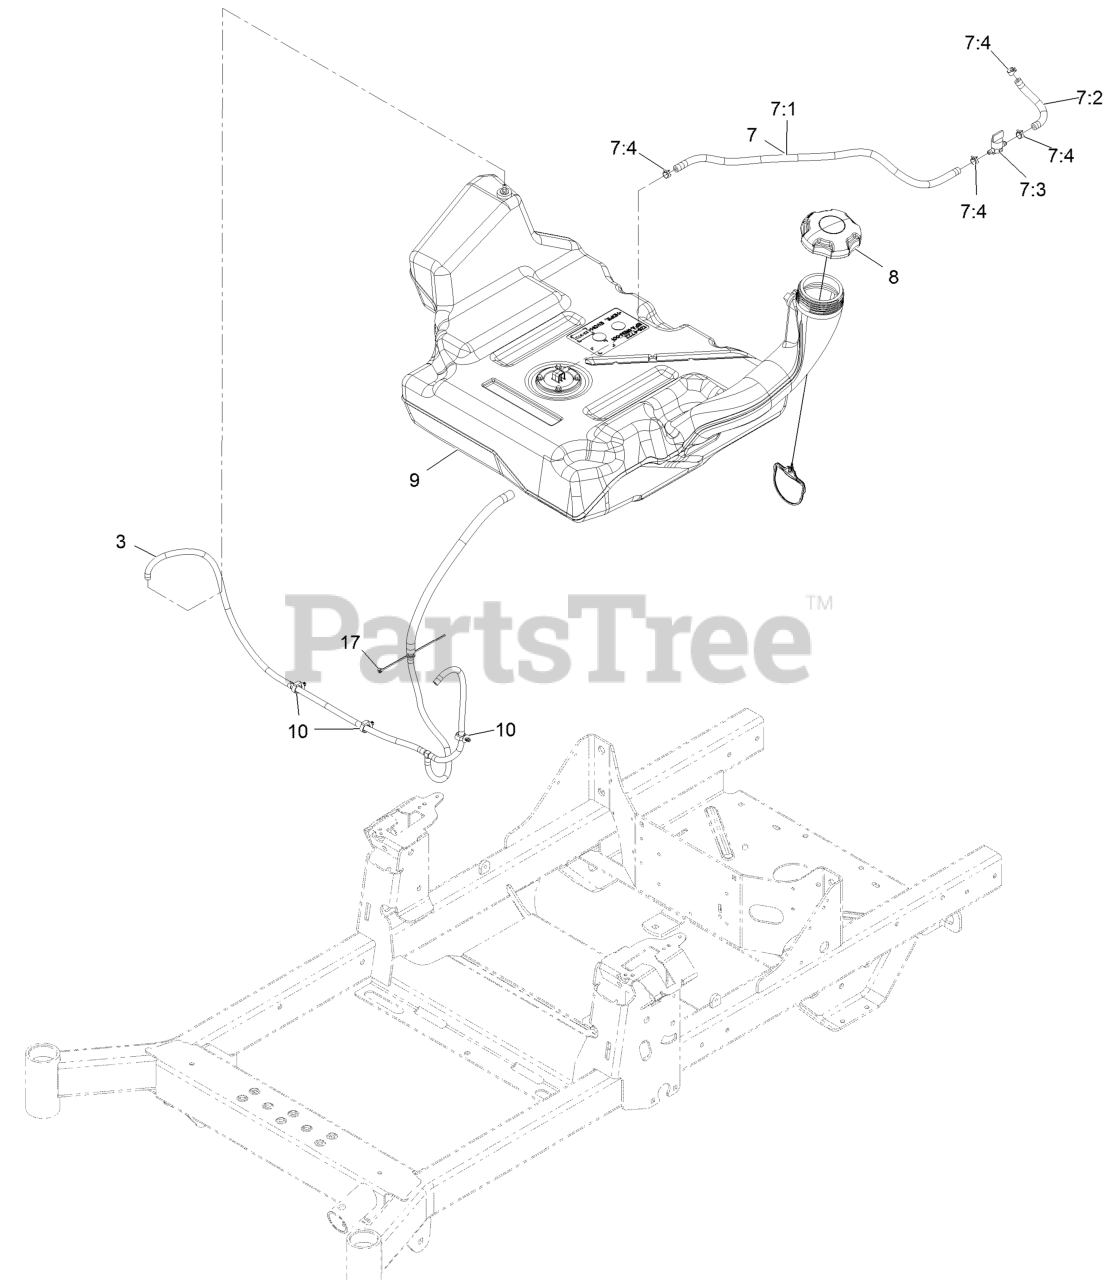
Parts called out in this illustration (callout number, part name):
3	Vent Hose ASM
7	Fuel Hose ASM
7:1	Hose-Fuel Line 24"
7:2	Hose-Fuel
7:3	Valve-Fuel
7:4	Clamp-Hose
8	Cap-Fuel
9	Tank-Fuel
17	Tie-Cable 5 1/2 (Small)
